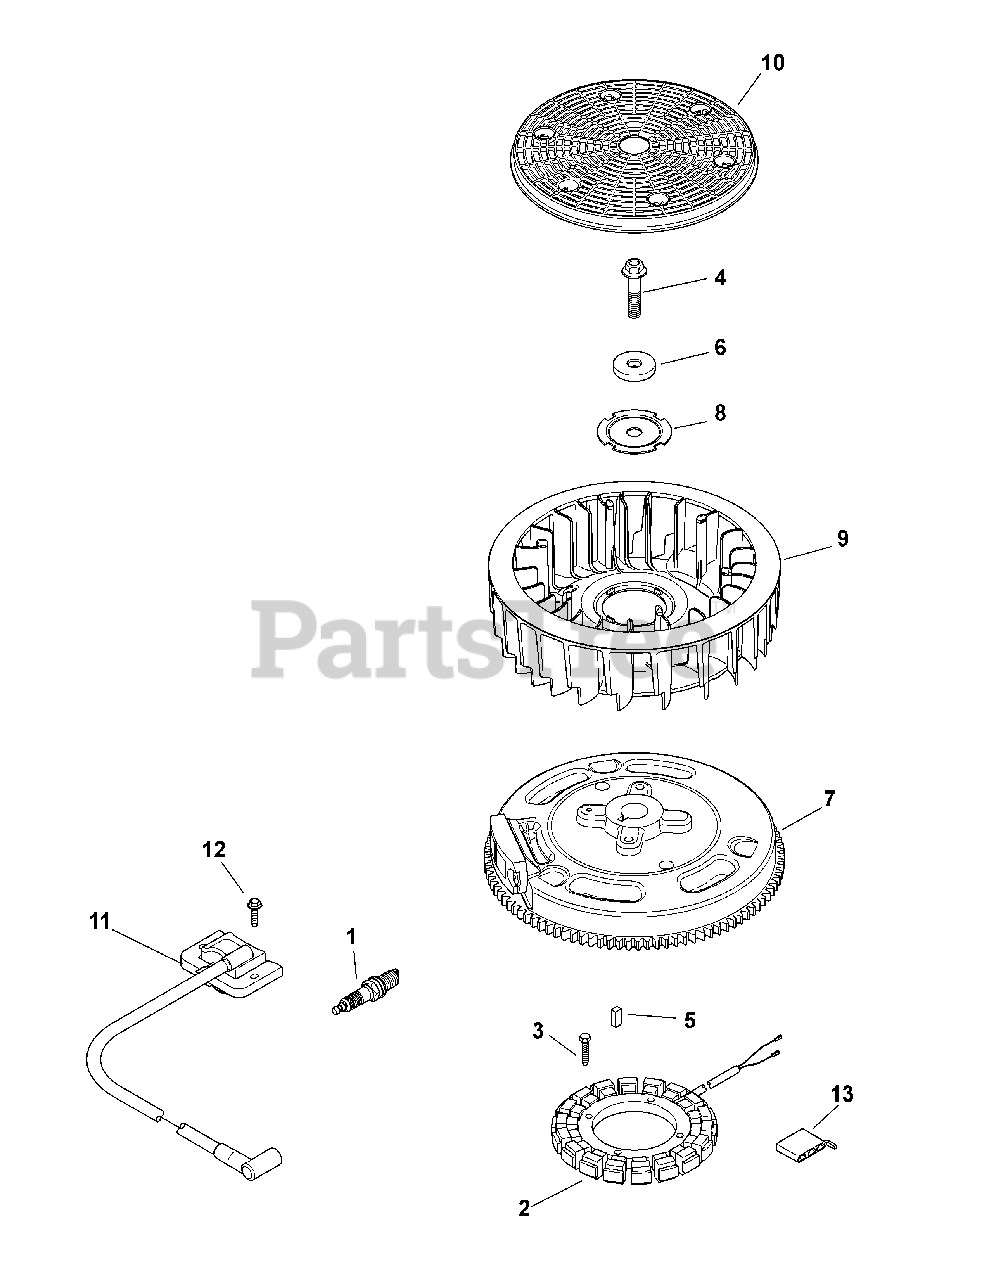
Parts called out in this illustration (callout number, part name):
1	Spark Plug
2	15 Amp Stator Kit
3	Screw, M5 x 0.8 x 25
4	Hex Flange Screw
7	Flywheel Assembly
8	Fan Mounting Plate
9	Fan
11	Module Ignition Kit
12	Screw, M5 x .8 x 20
